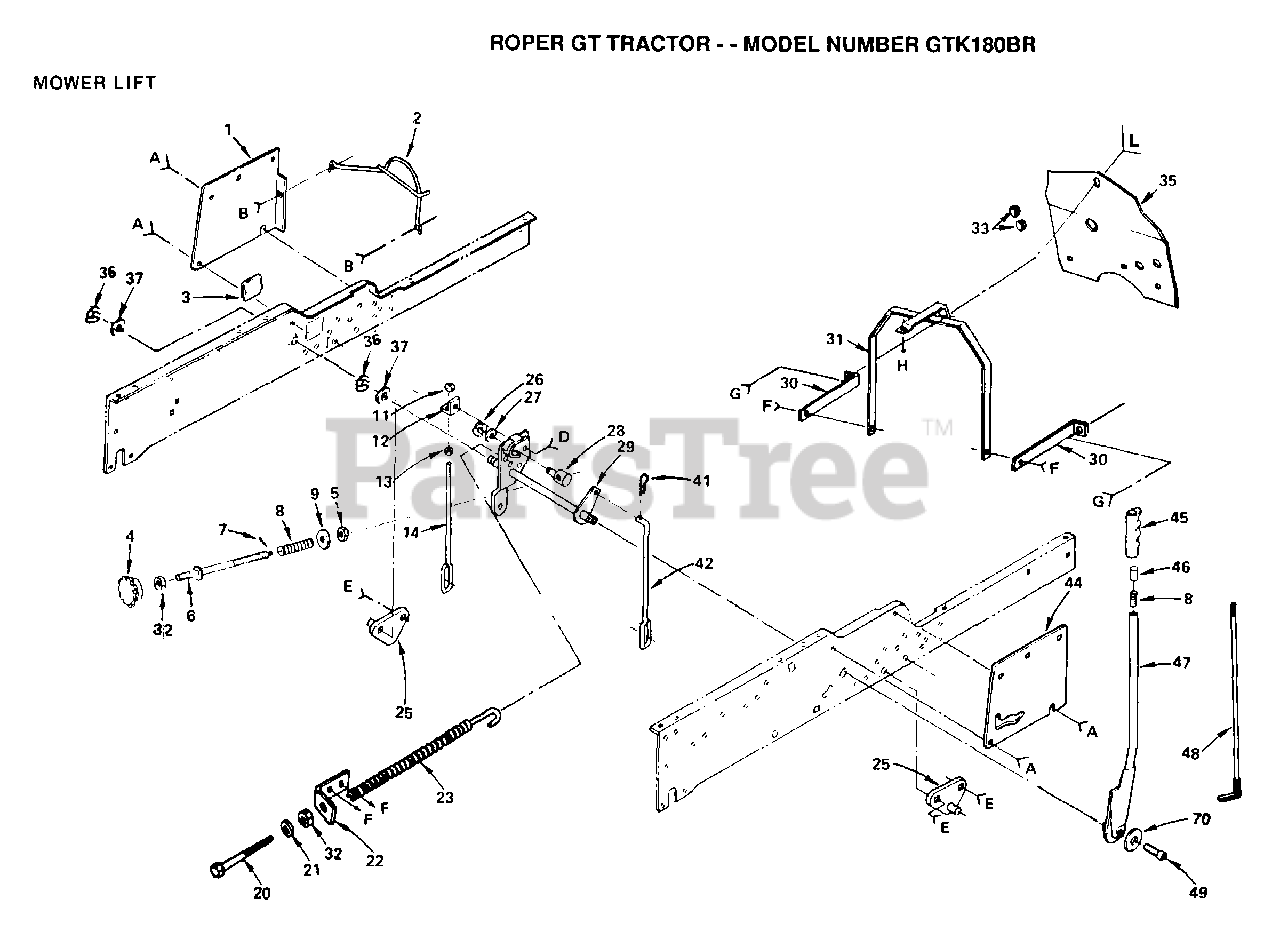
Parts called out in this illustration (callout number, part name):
3	COVER ACCESS
4	HDLE ADJ LIFT
5	NUT T
6	ROD ADJ. T
8	SPRING T
9	WASHER
11	NUT
12	BRACKET T
13	NUT.HEX.3/8-16UNC
14	LINK-LIFT MOW T
20	BOLT-ADJ SPRING T
21	WASHER
25	SUSP BRACKET T
26	KLIP RING
27	WASHER
28	TRUNION LT
30	BRACKET T
32	NUT
35	"SHIELD HEAT, BASE"
36	E-RING
37	WASHER
42	LIFT LINK RH T
45	GRIP
48	LEVER ROD LT
49	"BOLT,HEX"
70	LOCKWASHER
